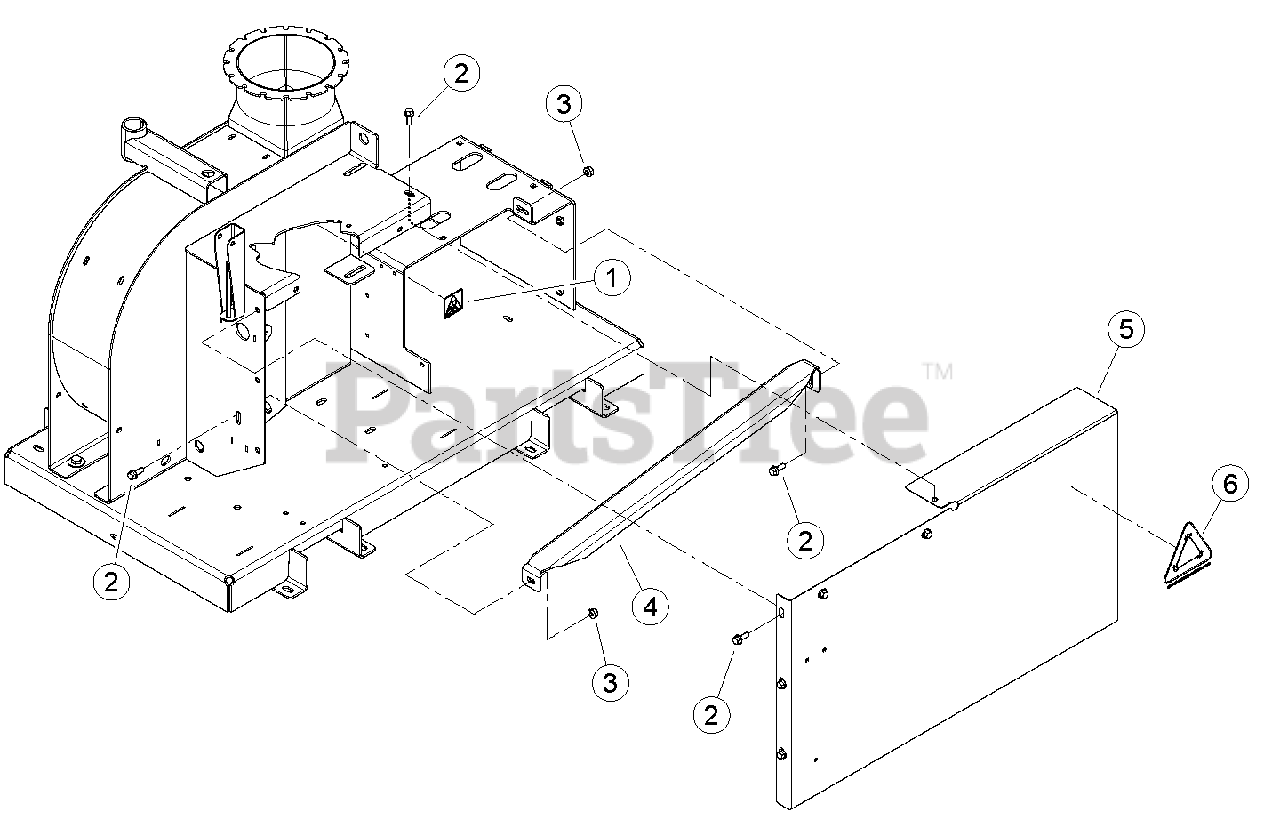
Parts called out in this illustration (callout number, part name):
1	DECAL, SHIELD DANGER ISO
2	BOLT, 3/8 X 1 FLANGE NC
3	NUT, 3/8-16 NYLOCK FLANGE
4	GUIDE, BELT
5	ASSEMBLY, BELT SHIELD
6	LOGO, COLLECT IT (WHITE)
